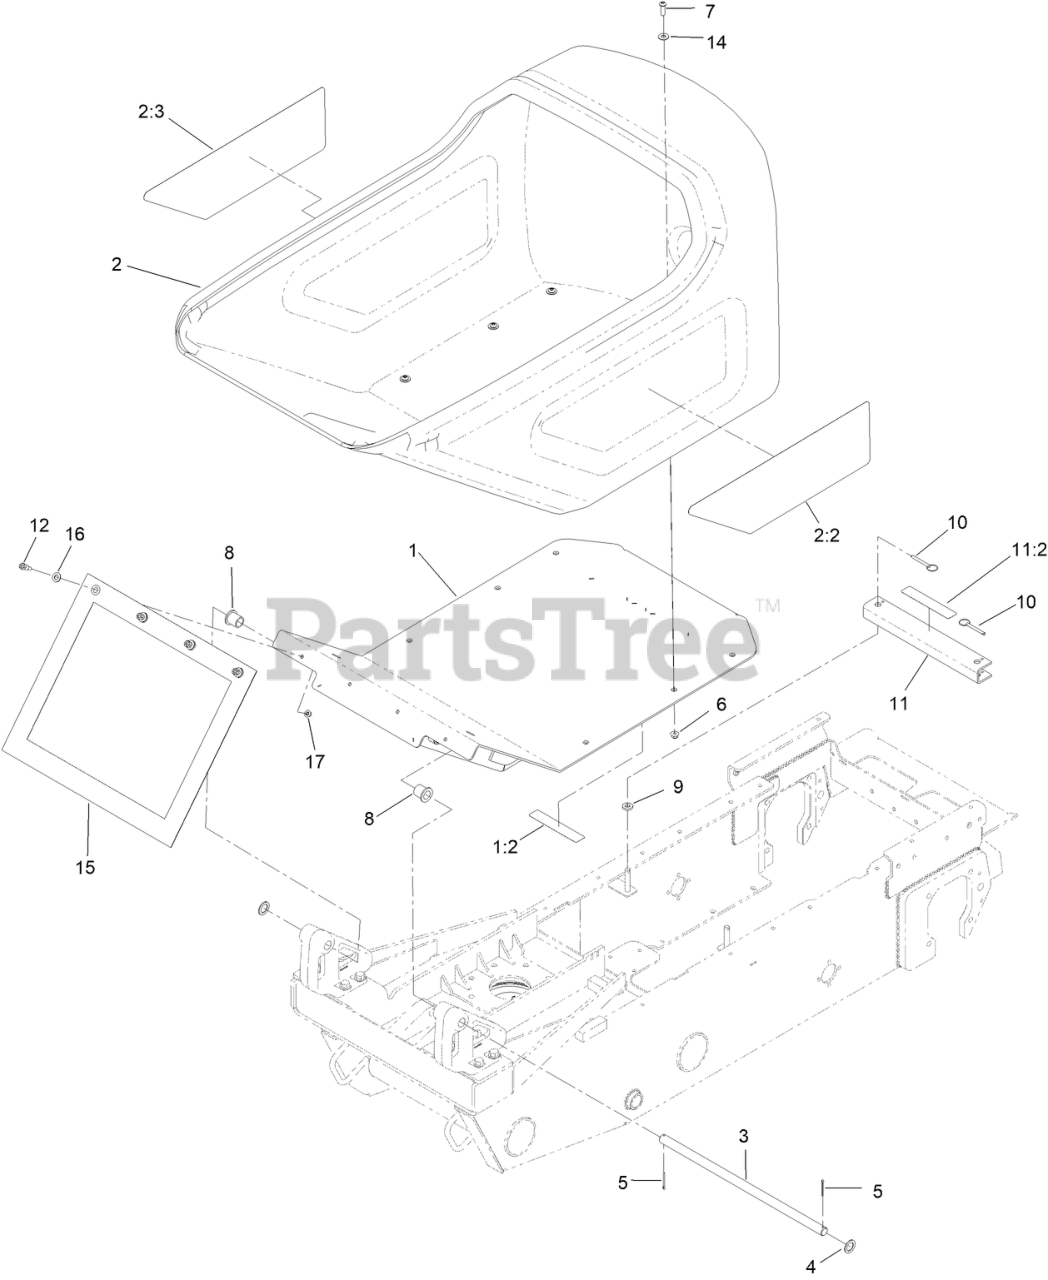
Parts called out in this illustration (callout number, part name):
1	HOPPER BASE ASM (SERVICE)
1:2	DECAL-DANGER
2	HOPPER-MORTAR ASM
2:2	DECAL-TUB, LEFT
2:3	DECAL-TUB, RIGHT
3	SHAFT-PIVOT,TUB
4	SPACER
5	PIN-COTTER
6	NUT-HF, NI
7	SCREW-HSBH
8	BEARING-FLANGED
9	WASHER-NEOPRENE
10	PIN-COTTERLESS
11	ARM-LOCKING
11:2	DECAL-DANGER
12	BOLT-SHOULDER
14	WASHER-FLAT
15	SHIELD-SPLATTER
16	WASHER-FLAT
17	NUT-HF, NI
